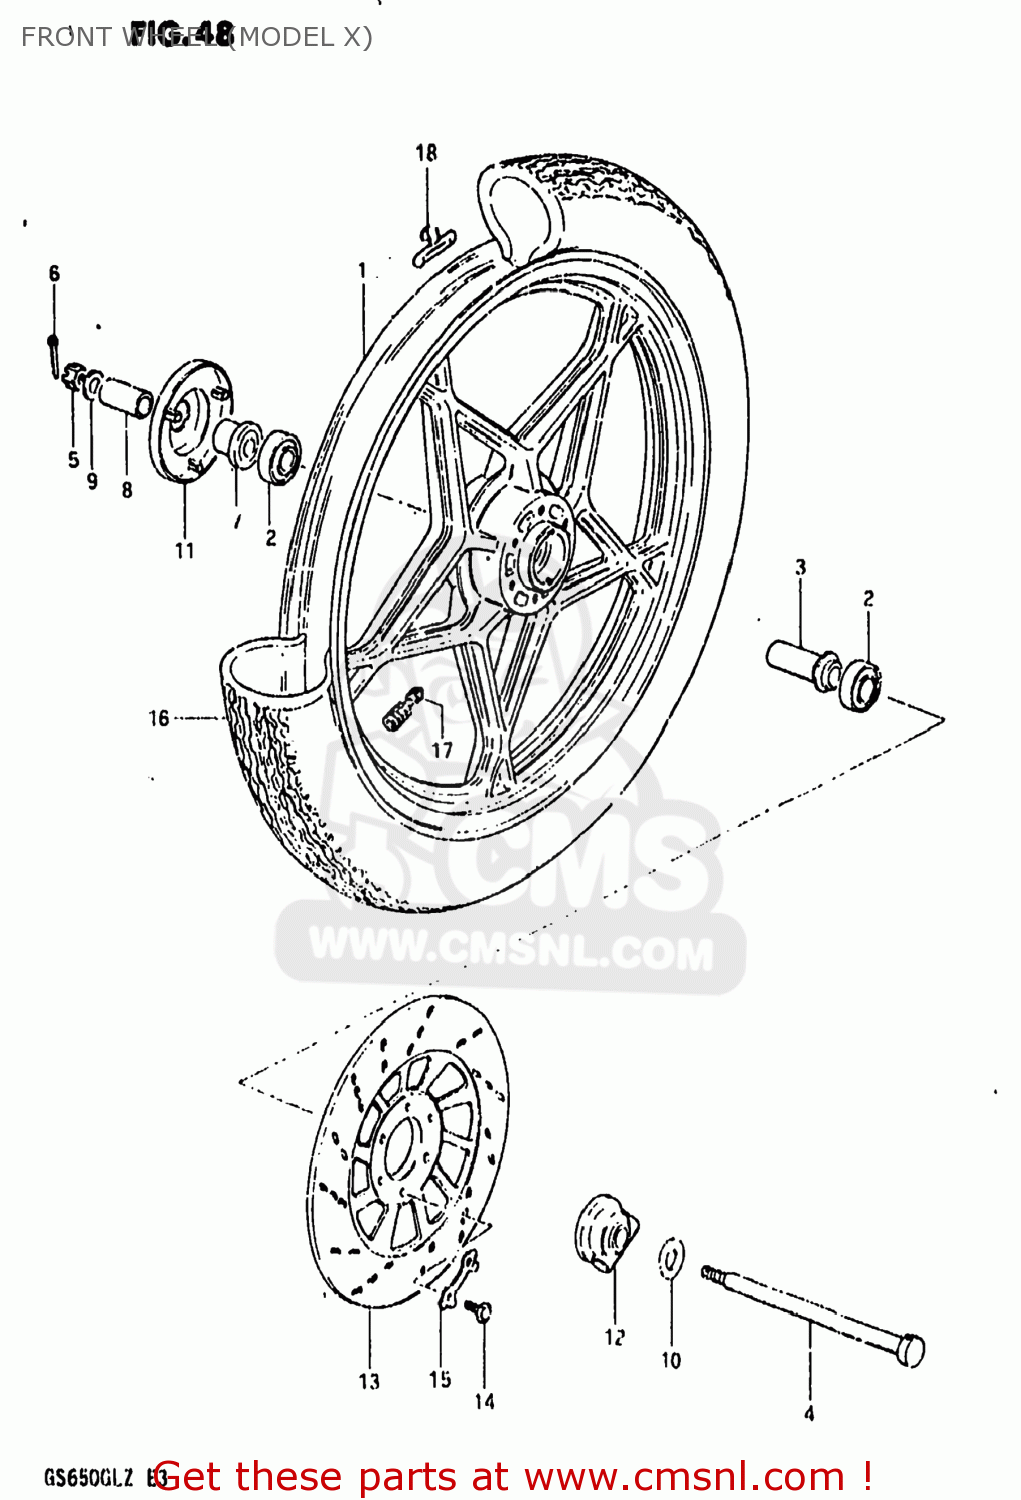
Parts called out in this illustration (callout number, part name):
1	CASTING WHEEL,FRONT 1.85
2	BEARING
3	SPACER,FR HUB BEARING
4	AXLE,FR
5	NUT 12MM
6	COTTER PIN
7	SPACER,FR AXLE,R
8	SPACER
9	WASHER
10	WASHER(15.5X26X2.3)
11	COVER,FR HUB,R
12	BOX ASSY,SPEEDOMETER GEAR
13	DISC,BRAKE
14	BOLT(8X25)
15	WASHER
16	TIRE,FRONT
17	VALVE ASSEMBLY,WHEEL RIM,J
18	BALANCER,WHEEL
